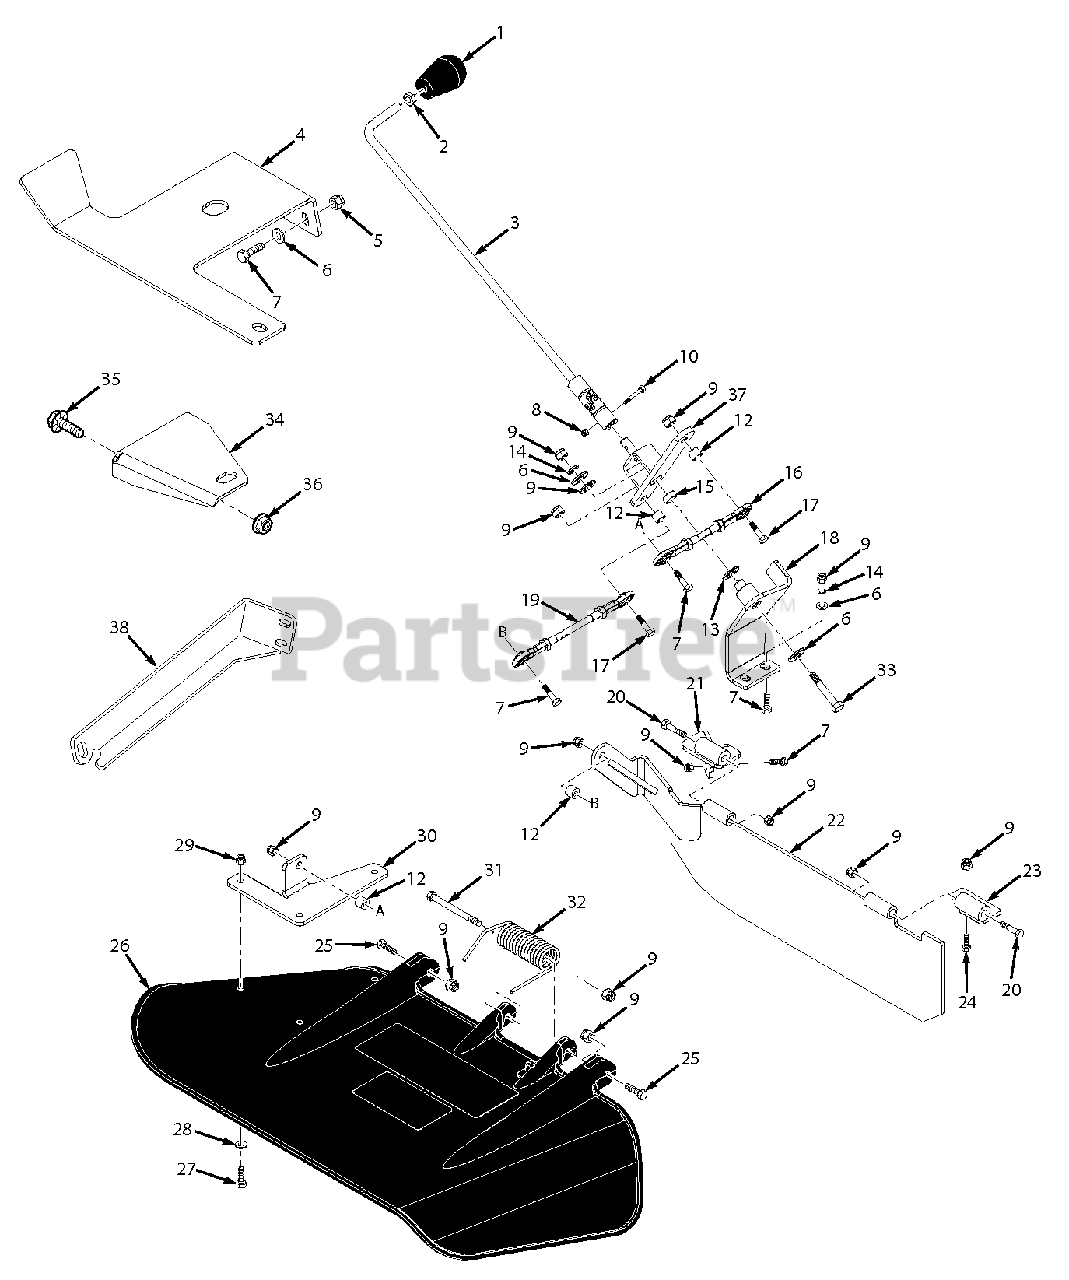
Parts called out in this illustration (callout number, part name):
1	Knob, Soft Touch
2	Nut, 3/8-16 UNC Jam
3	Lever Weldment, OCDC (STC/SCZ & STT)
3	Lever Weldment, OCDC (SVR)
4	Bracket, Lever Support (SCZ-48V & SCZ-52V)
4	Bracket, Lever Support (STC-48V & STC-52V)
4	Bracket, Lever Support (STC-61V)
4	Bracket, Lever Support (SCZ-61V)
5	Nut, Serrated Flange 5/16-18
6	Flatwasher, 5/16-.375 x .875 x .083
7	Bolt, Hex Head 5/16-18 x 1"
8	Nut, Elastic Stop #8-32
9	Nut, Elastic Stop 5/16-18
10	Capscrew, Socket Head #8-32 x 1-1/4"
11	Pivot Arm Weldment
12	Sleeve
13	Washer, Thrust 1/2" ID
14	Lockwasher, 5/16" Spring
15	Bearing
16	Linkage Assembly (SVR-48V)
16	Linkage Assembly (STC/SVR-52V)
16	Linkage Assembly (STC/SCZ-48V & SCZ/STT-52V)
16	Linkage Assembly (STC/SVR-61V)
16	Linkage Assembly (SCZ/STT-61V)
17	Bolt, Hex Head 5/16-18 x 1-1/2"
18	Pivot Weldment (SVR-48V, STC/SVR/SCZ/STT-52V)
18	Pivot Weldment (STC/SCZ-48V)
18	Pivot Weldment (STC/SVR-61V)
18	Pivot Weldment (SCZ/STT-61V)
19	Linkage Assembly (SVR-48V)
19	Linkage Assembly (STC/SCZ-48V)
19	Linkage Assembly, (STC/SVR-52V)
19	Linkage Assembly (SCZ/STT-52V)
19	Linkage Assembly (STC/SVR-61V)
19	Linkage Assembly (SCZ/STT-61V)
20	Bolt, Hex Head 5/16-18 x 3-1/2"
21	Hinge Weldment, Rear (48V)
21	Hinge Weldment, Rear (52V & 61V)
22	Block-Off Plate Weldment (48V)
22	Block-Off Plate Weldment (52V)
22	Block-Off Plate Weldment (61V)
23	Hinge Weldment, Front
24	Bolt, Hex Head 5/16-18 x 3/4"
25	Bolt, Hex Head 5/16-18 x 1-3/4"
26	Discharge Chute Assy., 48V
26	Discharge Chute Assy., 52V
26	Discharge Chute Assy., 61V
27	Bolt, Hex Head 1/4-20 x 3/4"
28	Flatwasher, 1/4-.312 x .750 x .065
29	Nut, Elastic Stop 1/4-20
30	Plate, Discharge Chute (48V)
30	Plate, Discharge Chute (52V)
30	Plate, Discharge Chute (61V)
31	Bolt, Hex Head 5/16-18 x 4-3/4"
32	Spring, Discharge Chute
33	Bolt, Hex Head 5/16-18 x 2"
34	Guide Bracket, OCDC Lever (STT-52V & STT-61V)
35	Bolt, 5/16-18 x 3/4" Serrated Flange
36	Nut, 5/16-18 Serrated Flange
37	Pivot Arm Weldment (SVR-48V/52V/61V, STC-52V/61V, SCZ-52V/61V, STT-52V/61V)
37	Pivot Arm Weldment (STC/SCZ-48V)
38	Bracket, Lever Support (SVR)
